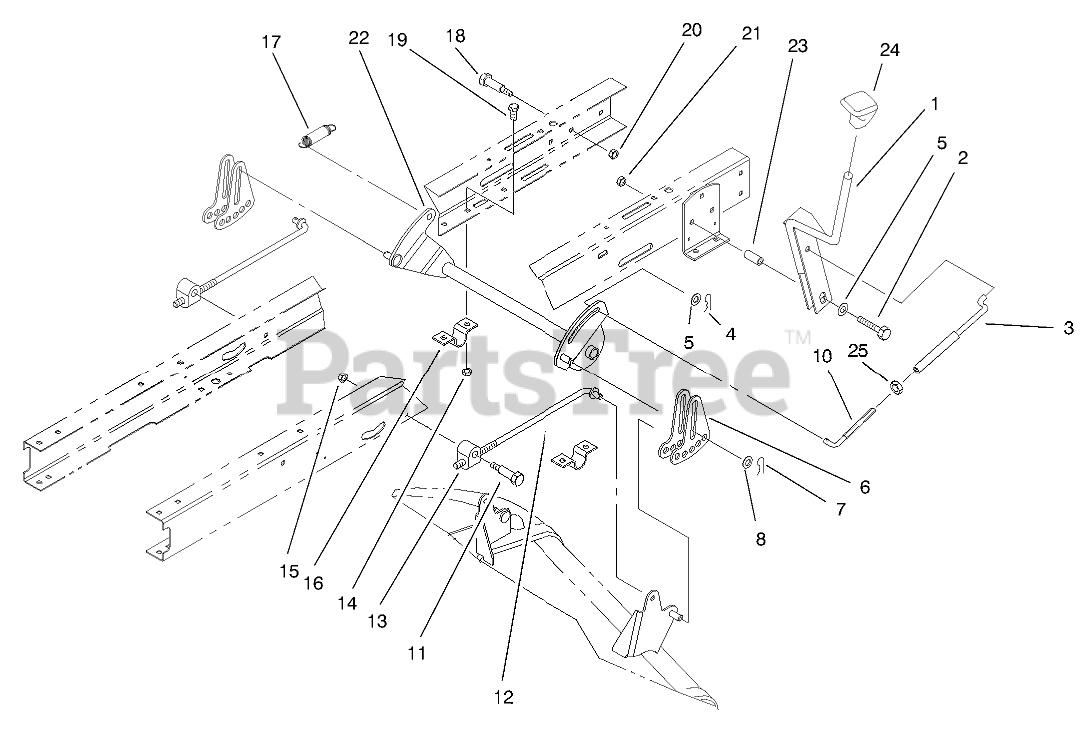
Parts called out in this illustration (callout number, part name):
1	HOC LEVER ASM
2	SCREW-HH
4	PIN-COTTER
5	WASHER-FLAT
6	LINK-ADJUSTING, HOC
7	PIN-COTTER
8	WASHER-HARDENED
10	LINK-HOC
11	SCREW-SHOULDER, HH
12	ROD-HANGER, REAR
13	TRUNNION-HOC
14	NUT-LOCK, NI
15	NUT-LOCK, NI
16	CLAMP-PIVOT, HOC
17	SPRING-EXTENSION
18	SCREW-SHOULDER, HH
19	SCREW-HH
20	NUT-LOCK, NI
21	NUT-LOCK, NI
22	PIVOT-HOC
23	SPACER
24	KNOB-SHIFT
25	NUT-JAM
